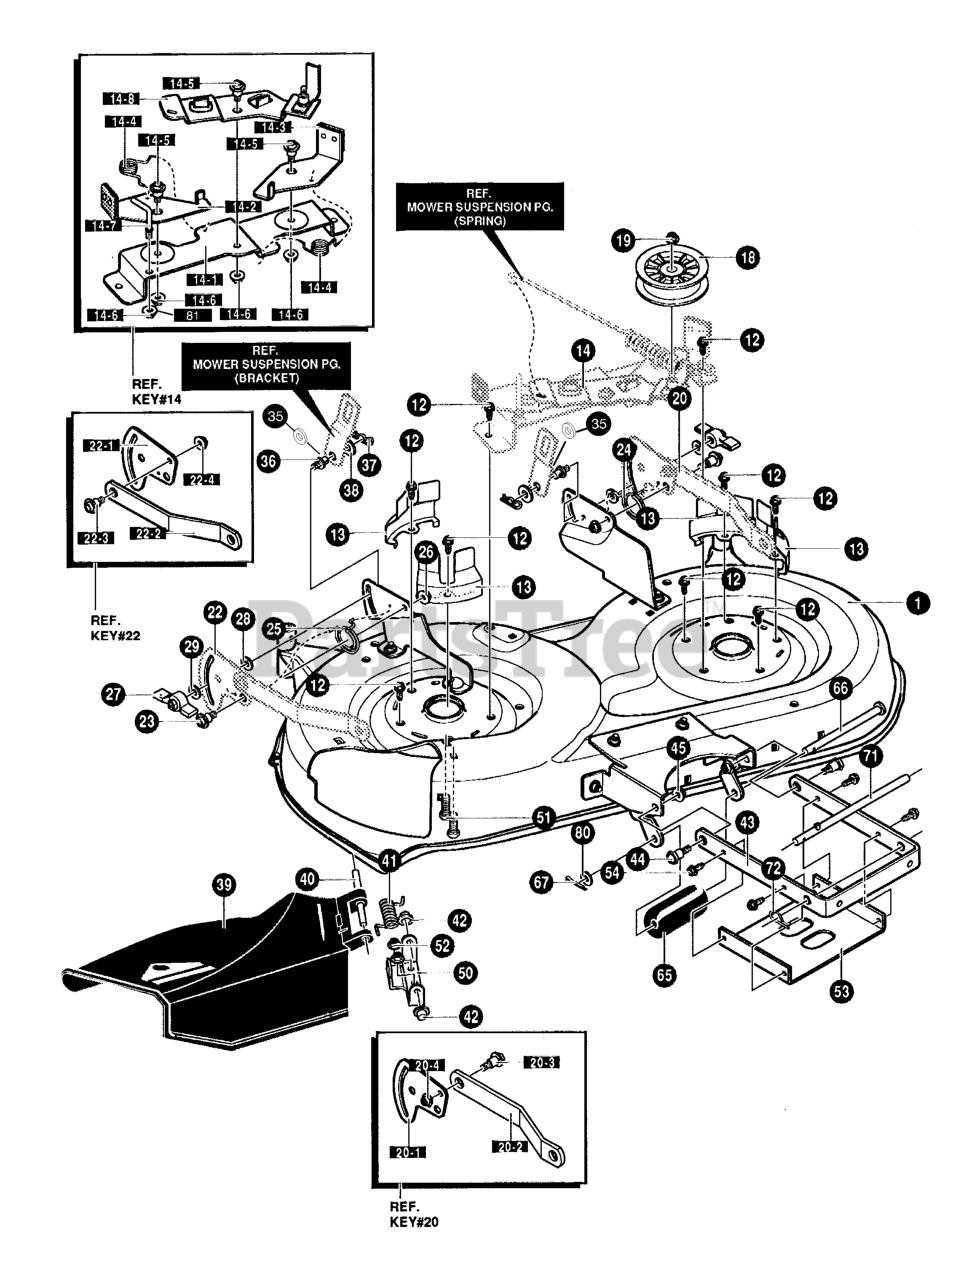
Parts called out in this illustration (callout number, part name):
1	ASSY 42" MOWER DECK
12	SCREW, 3/8-16 x 1 .25
13	COVER, SEGMENT BELT GUIDE
14-1	BRACKET, BRAKE MT
14-2	ASSY BRAKE RH
14-3	ASSY BRAKE RH
14-4	TORSION SPRING
14-5	BOLT.50X.75
14-6	NUT, 3/8-16
14-7	SCREW GUIDE
14-8	ASSY IDLER ARM
18	PULLEY, IDLER
19	NUT, 3/8-16
20	PLATE, REAR SUS. BRKT. LH
20-1	PLATE - SUSPENSION
20-2	SUSPENSION BRKT REAR
20-3	BOLT, SHOULDER 3/8-16
20-4	NUT, 3/8-16
22	PLATE, REAR SUS. BRKT. RH
22-1	PLATE - SUSPENSION
22-2	SUSPENSION BRKT REAR
22-3	BOLT, SHOULDER 3/8-16
22-4	NUT, 3/8-16
23	BOLT, SHOULDER
24	SPRING, TORSION
25	SPRING, TORSION
26	NUT, 3/8-16
28	PAD, FRICTION
35	WASHER, WAVE
36	PIN, HANGER
37	PIN, HAIR
38	WASHER, FLAT
39	CHUTE DEFLECTOR
40	ROD, CHUTE DEFLECTOR
41	SPRING, TORSION
42	NUT, PUSH CAP
43	BRACKET, FRT SUSPENSION
44	BOLT, SHOULDER
45	NUT, 3/8-16
50	BRACKET, CHUTE
51	BOLT, 5/16-18X.63
52	NUT, 5/16-18
53	STIFFENER NLT
54	SCREW, 5/16-18 x 0.75
66	ROD, SUPPORT
67	PIN, COTTER
71	ROD HANGER
72	HAIR PIN
80	FLATWASHER
81	NUT, HEX
